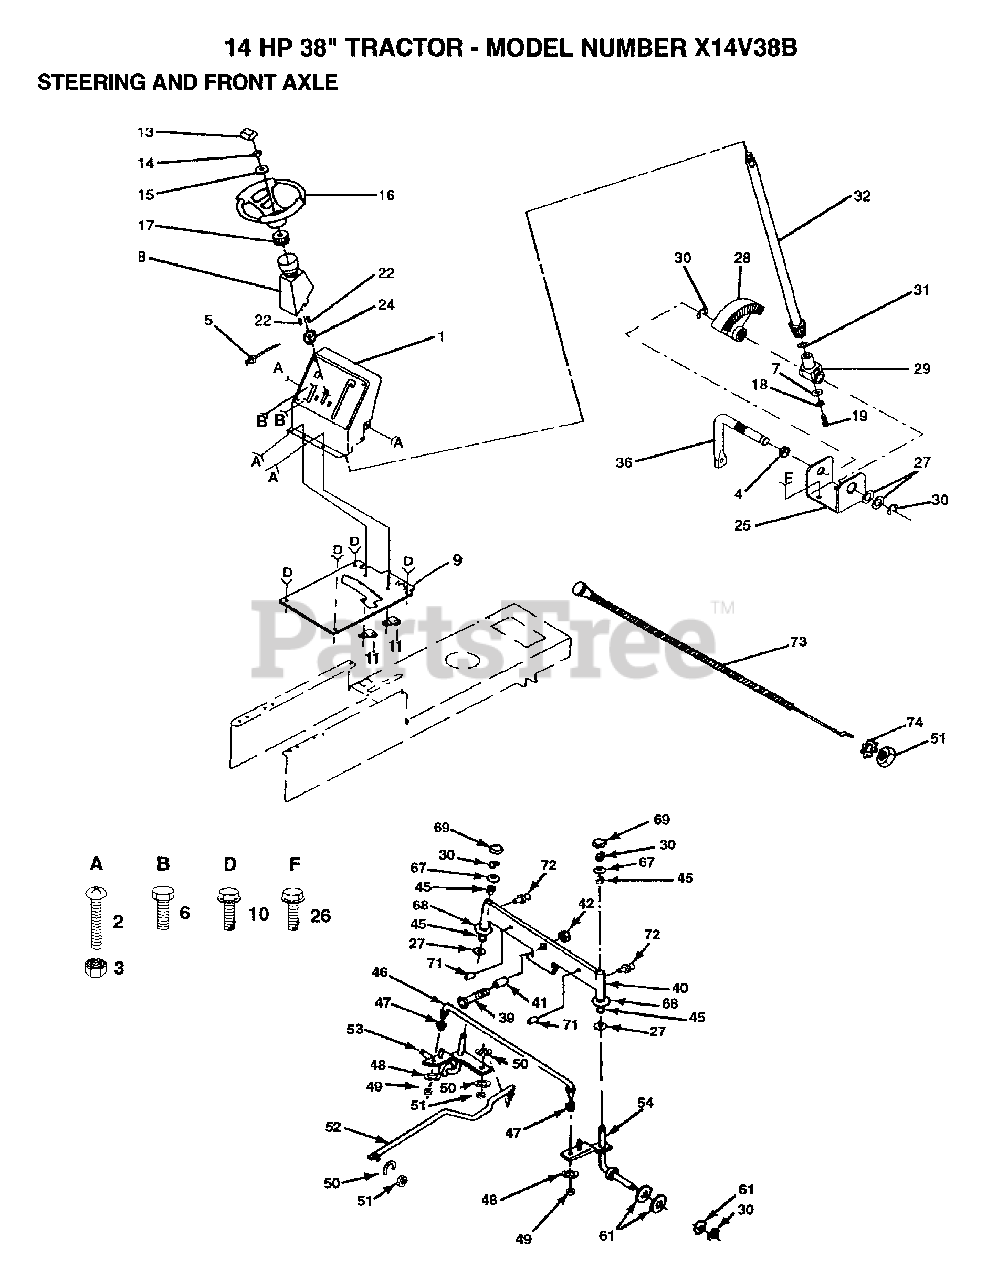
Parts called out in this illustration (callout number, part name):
2	SCREW
4	NYLINER T
6	SCREW LT
8	BOOT STR SHAFT
10	SCREW LT
11	CLIP T
13	ST WHL INSERT CAP
14	GRIPCO NUT
15	WASHER T
17	ADAPTER-WHEEL LT
18	LOCKWASHER
19	"SCREW,SPECIAL"
25	"BRKT,STEERING"
26	SCREW
27	WASHER .T
29	SUPPORT.SHAFT
30	RING
31	THRUST WASHER
32	SHAFT ASM
39	BOLT HEX 5/8-11
41	BEARING
45	COL. SRTG. BEAR.
46	TIE ROD
47	WASHER M
48	LOCKWASHER
49	NUT.LOCK.5/16-24
50	LOCKWASHER
53	SPINDLE LH
54	SPINDLE RH
61	WASHER
67	WASHER
68	WASHER
69	CAP
71	AXLE PIN
74	LOCKWASHER
